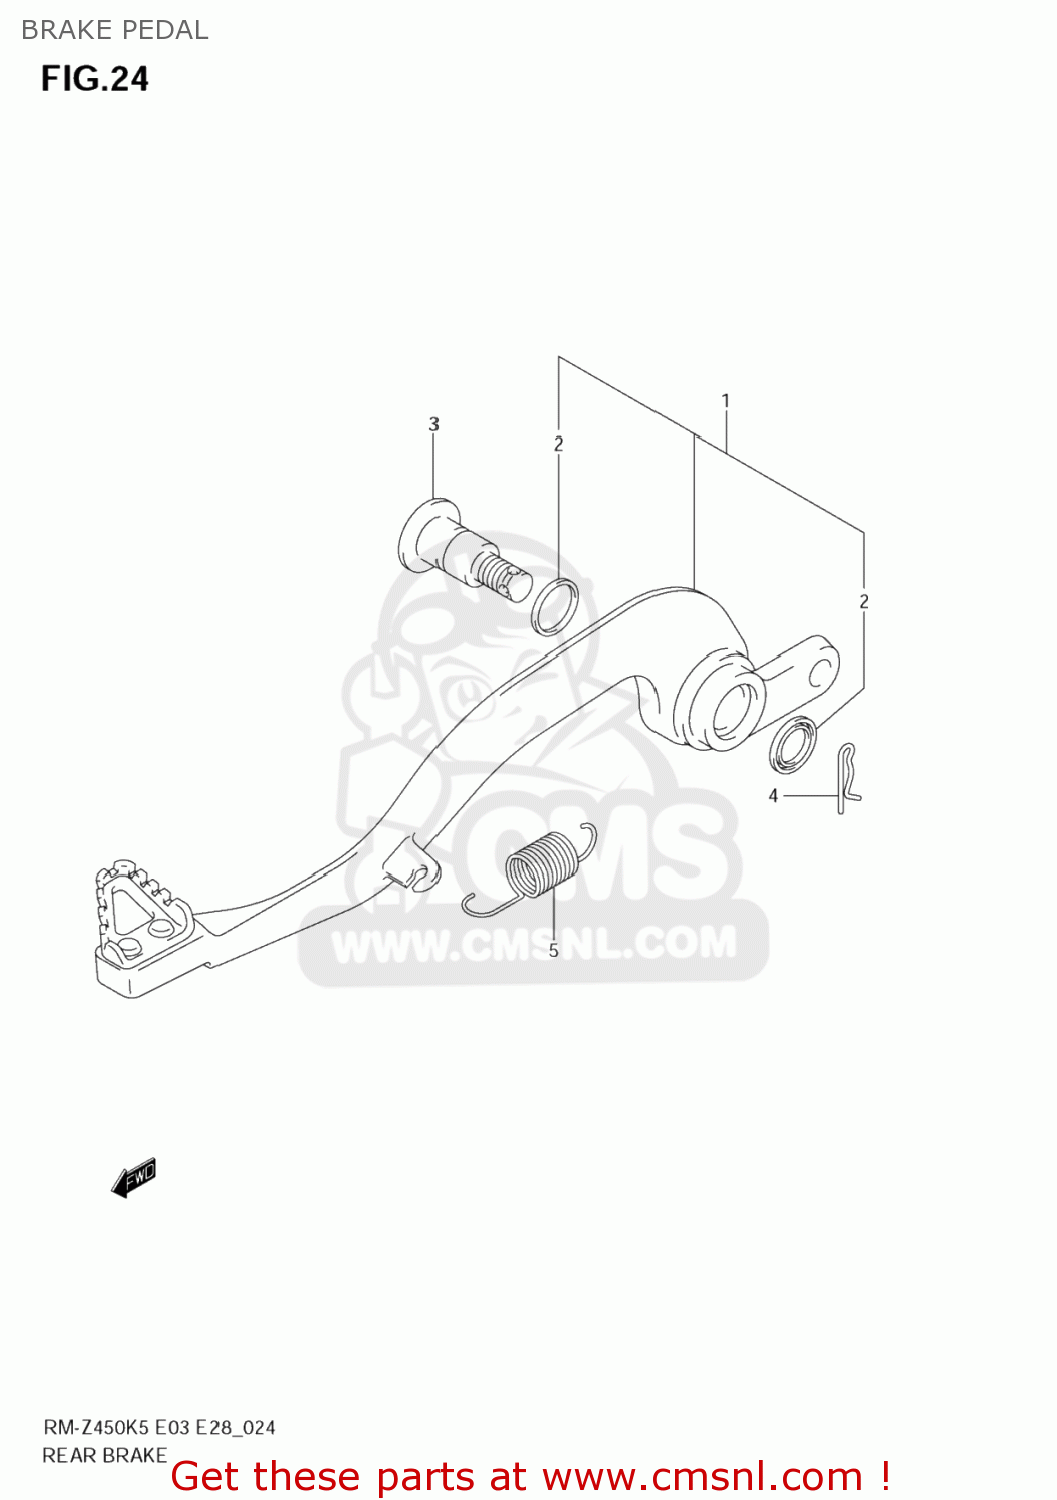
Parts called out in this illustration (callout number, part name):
1	PEDAL ASSY,BRAKE
2	SEAL,OIL(15X21X3)
3	SHAFT,BRAKE PEDAL
4	CLIP
5	SPRING
